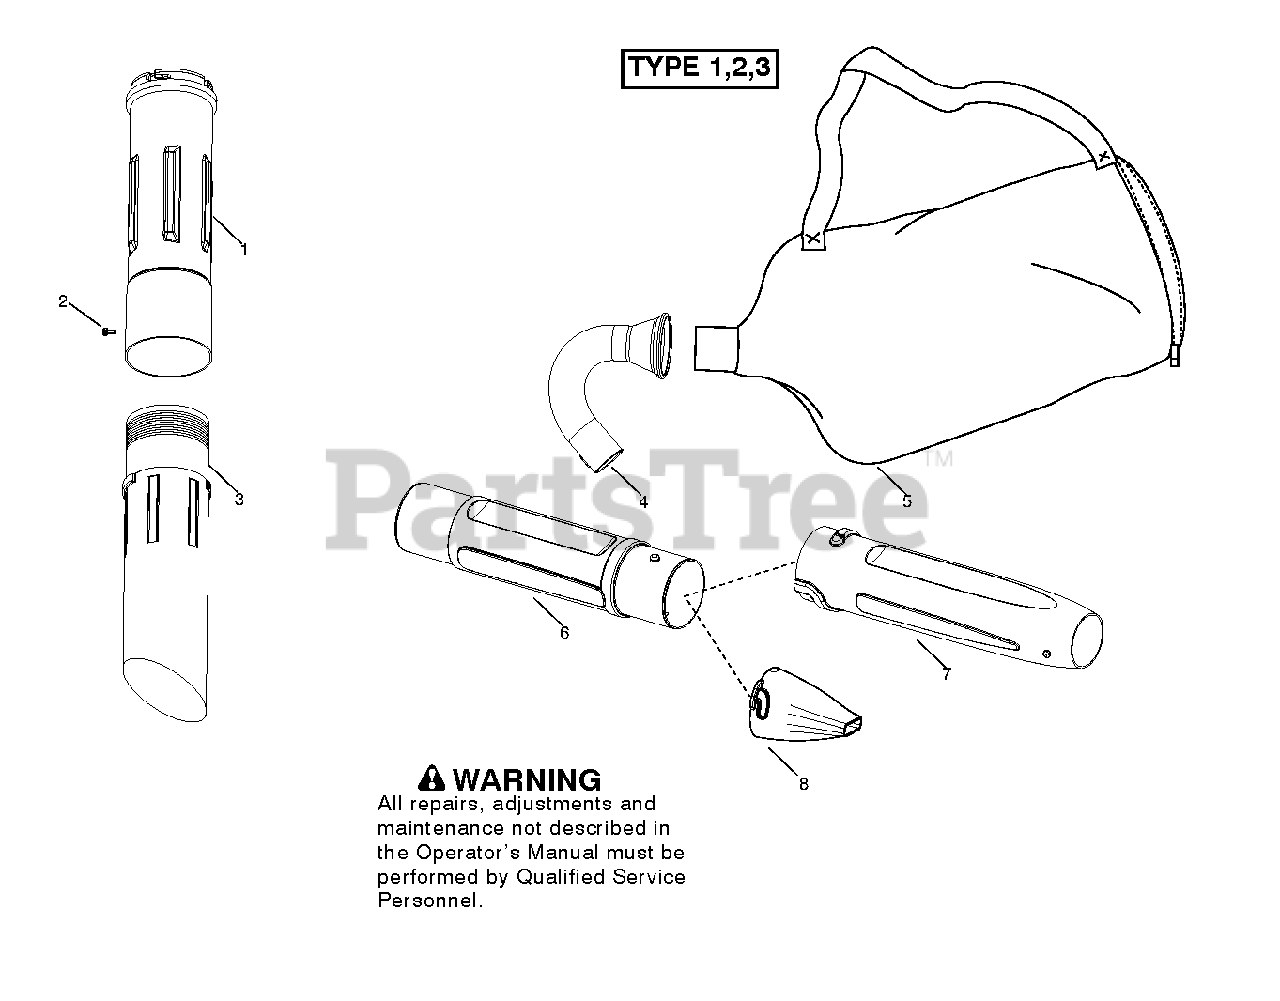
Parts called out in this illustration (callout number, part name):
1	TUBE VAC UPPER BLACK
5	ASSY VAC BAG GAS W/STRAP
6	TUBE
7	Lower Blower Tube, Round P/S
8	NOZZLE BLACK HI SPEED ADAPTOR
